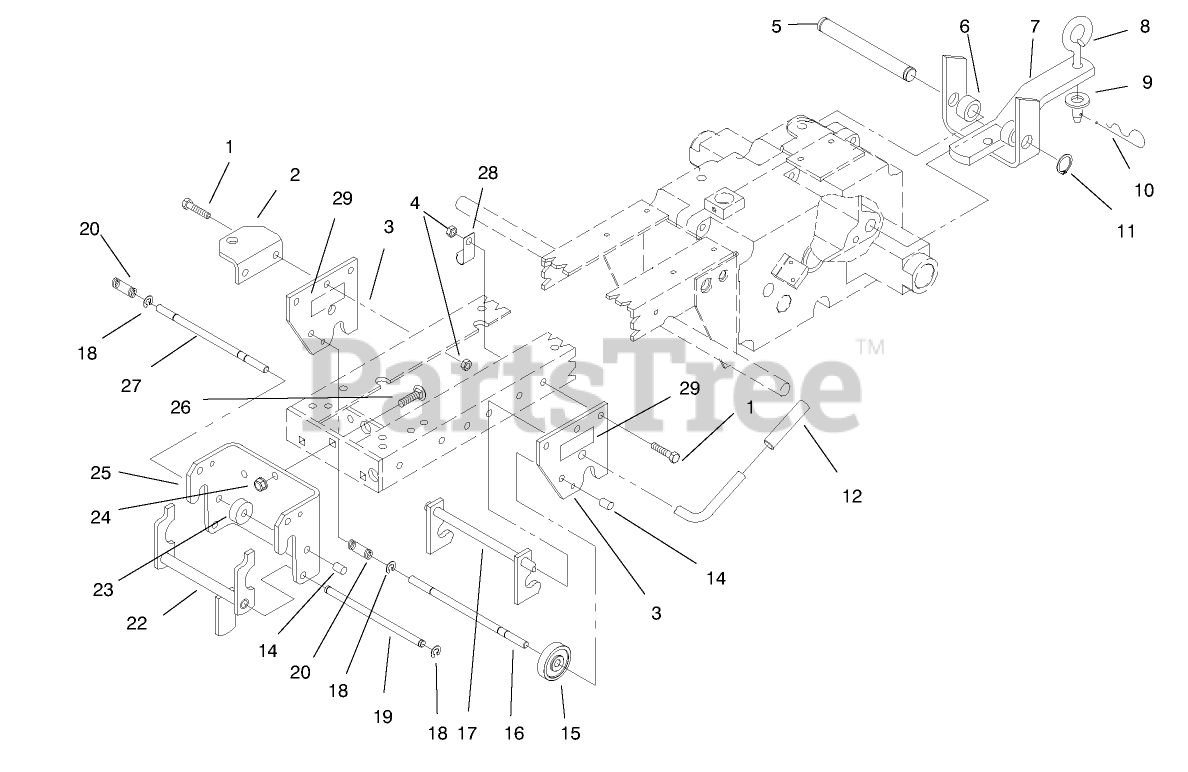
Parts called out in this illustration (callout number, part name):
1	SCREW-HH
2	SUPPORT
3	PLATE-HITCH
4	NUT-HEX
5	PIN-STATIONARY HITCH
6	SPACER
8	PIN-TOOL
9	WASHER-FLAT
10	PIN-HAIR
11	E-RING
12	GRIP
14	CAP-ROD, PLUNGER
16	ROD-LOCK
17	MID HITCH ASM
18	RING-RETAINING
19	ROD-LATCH PIVOT
20	SPRING
22	LATCH
24	NUT-LOCK, NI
25	HITCH-FRONT
26	BOLT-CARR
27	ROD-LOCK
28	CLIP
29	DECAL-ATTACH A-MATIC
